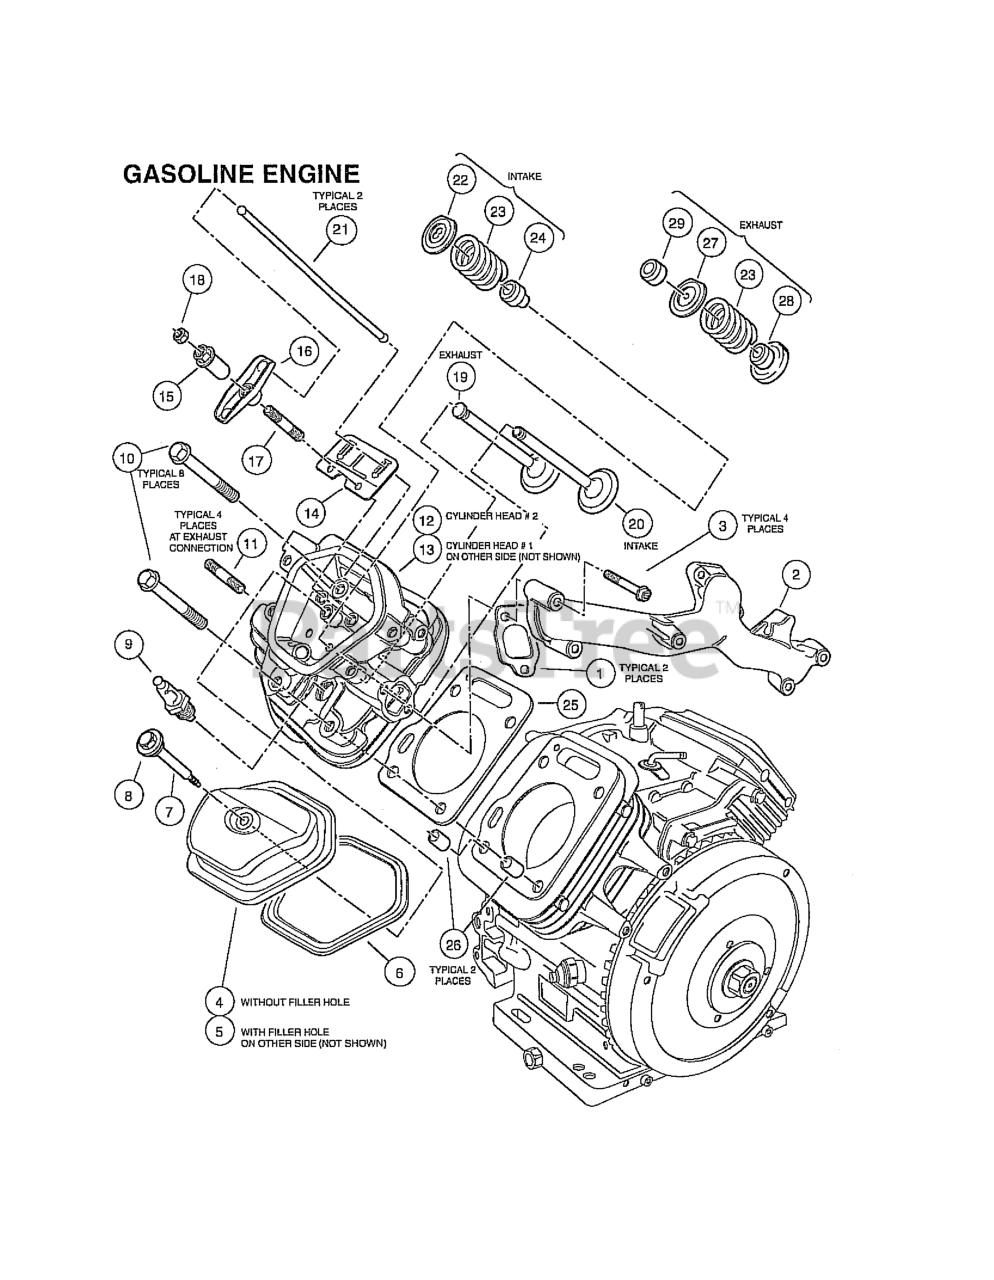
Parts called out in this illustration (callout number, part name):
1	GASKET, IN. MANIFOLD
2	MANIFOLD, IN
3	BOLT, SOCKET, M8 X 1.25 X 45
4	COVER, HEAD
5	COVER, HEAD FILLER
6	GASKET, CYLINDER HEAD COVER
7	BOLT, HEAD COVER
8	WASHER, HEAD COVER
9	SPARK PLUG, BPR2ES,NGK
10	BOLT, FLANGE, M10 X 1.5 X 80
11	BOLT, STUD, M8X22
12	CYLINDER HEAD, #2
13	CYLINDER HEAD, #1
14	PLATE, PUSH ROD GUIDE
15	PIVOT, ROCKER ARM
16	ARM, VALVE ROCKER
17	BOLT, PIVOT, M8
18	NUT, PIVOT ADJ
22	RETAINER, IN VALVE SPRING
23	SPRING, VALVE
24	SEAL, VALVE STEM
25	GASKET, CYLINDR HEAD
26	PIN A, DOWEL, 12 X 20
27	RETAINER, EX VALVE SPRING
28	SEAT, VALVE SPRING
29	ROTATOR, VALVE
